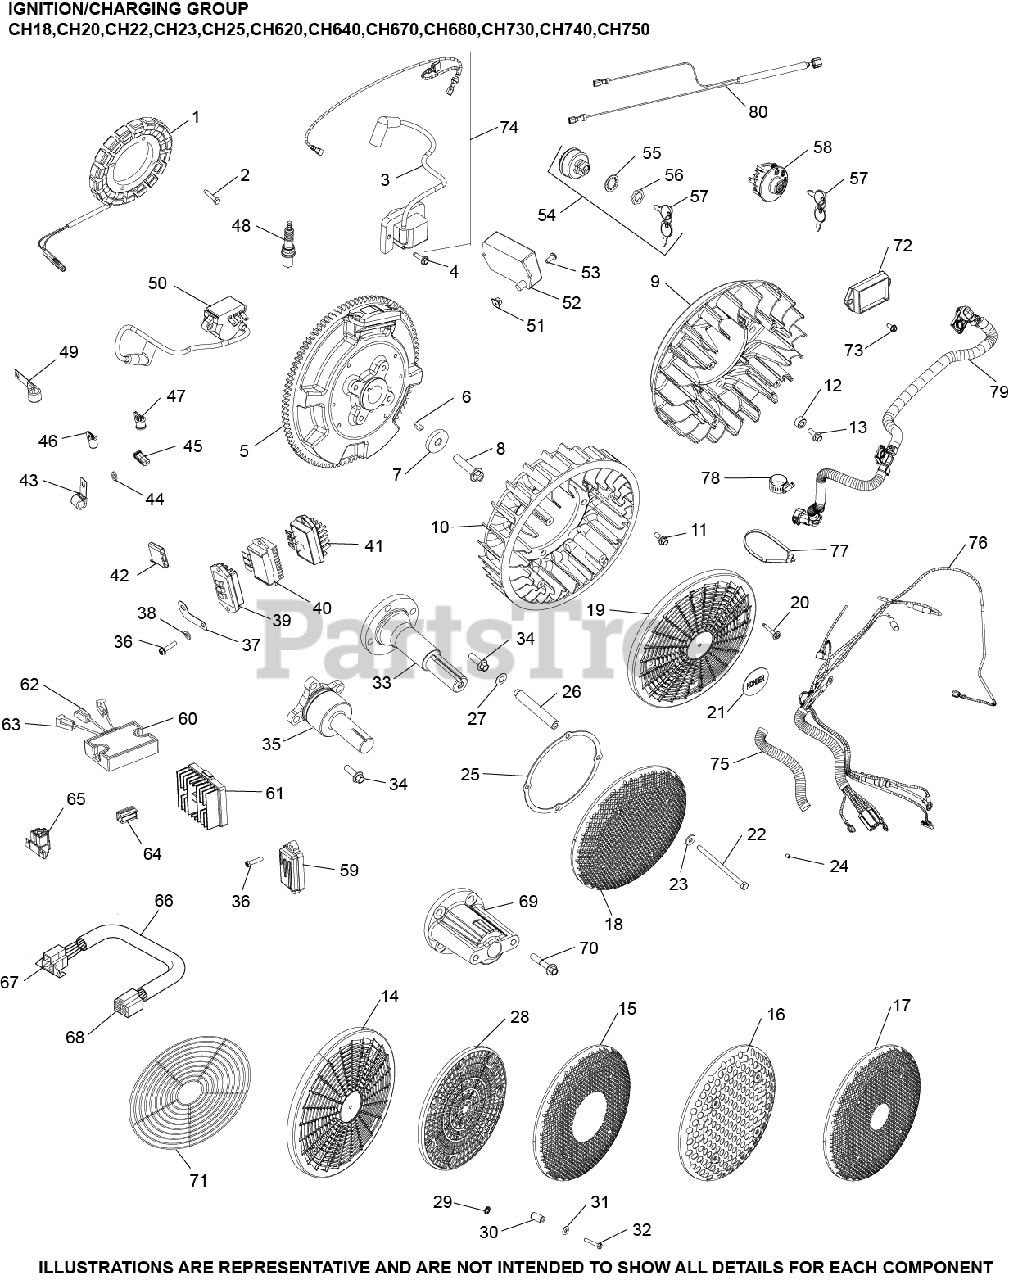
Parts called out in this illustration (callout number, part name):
1	KIT, 15 / 20 AMP STATOR
2	SCREW, THREAD FORMING
3	KIT, MODULE IGNTN (CDI FIXED)
4	SCREW, THREAD FORMING - USE 25 086 473-S
6	KEY, 3/16" X 5/8"
7	WASHER, FLAT 13/32"
8	SCREW, FLG M10X1.5X45 - (#25086361S)
10	FAN USE 24 755 253-S
16	SCREEN, GRASS
22	SCREW, SOCKET TRUSS HD CAP
23	WASHER, FLAT 1/4" (O.D. 5/8")
24	SCREW, SKT SET #10-24X1/4"
25	RING, SUPPORT USE 25 141 08-S
27	WASHER, SPRING 10 MM
33	SHAFT, FRONT DRIVE
34	SCREW, FLG M8X1.25X25
36	SCREW, HEX FLANGE HI-LO
37	BRACKET, GROUND STRAP USE 24 518 12-S
39	REGULATOR/RECTIFIER
42	CONNECTOR
43	CLIP, CABLE
44	WASHER, FLAT 1/4" (O.D. 1/2")
48	PLUG, SPARK (STD)
76	HARNESS, WIRING ASSEMBLY
